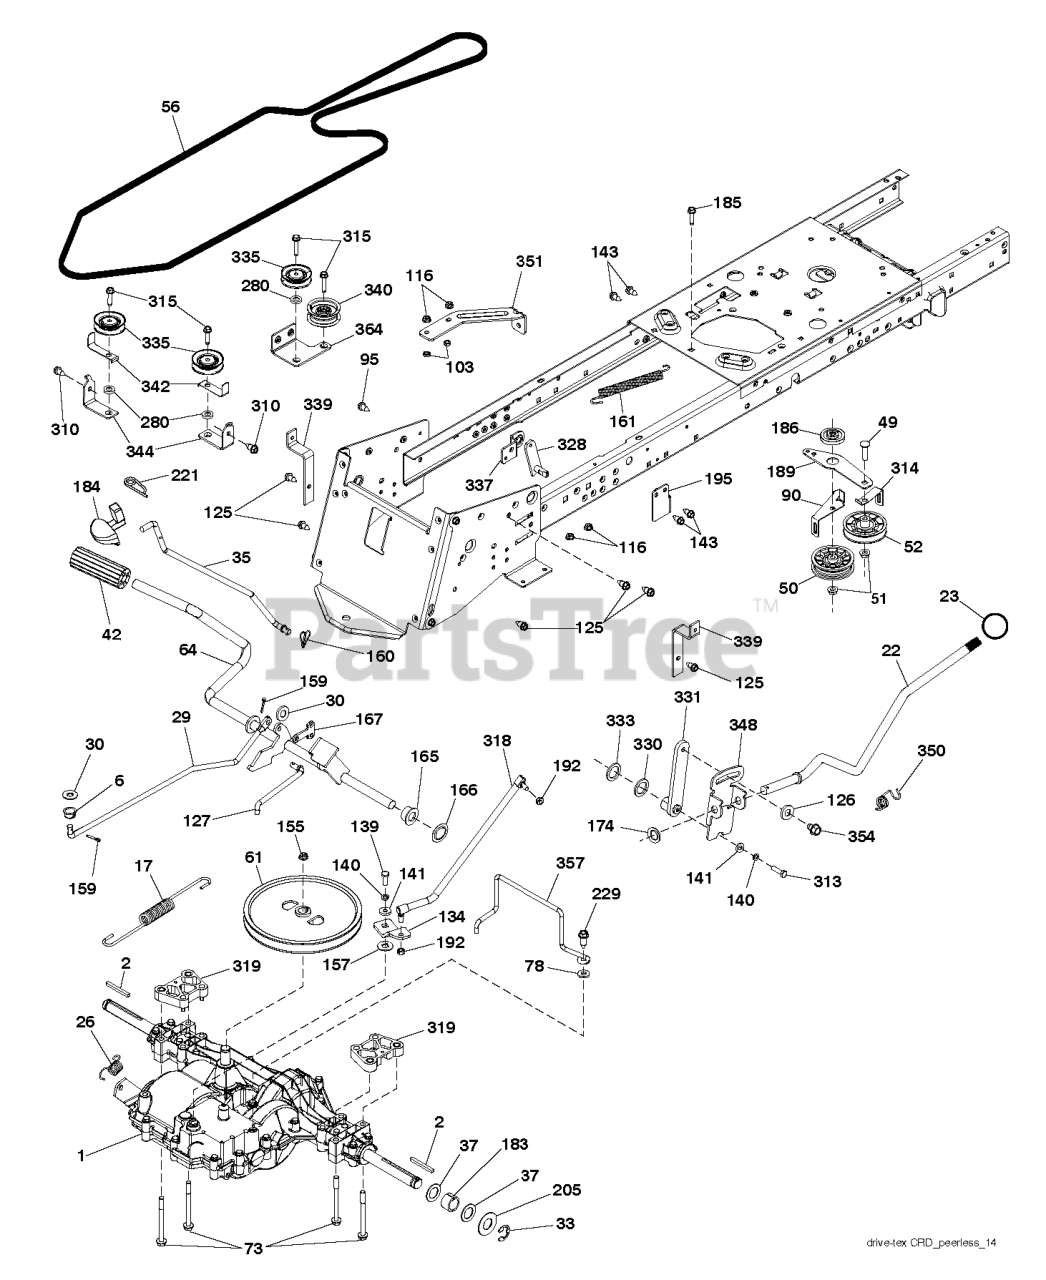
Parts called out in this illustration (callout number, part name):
2	SQUARE KEY
6	BUSHING.SNAP.NYL.BLK.
17	SPRING SPRING BRAKE GEAR CRD
22	ROD ROD SHIFT CRD TEX
23	KNOB.DUCKHEAD.1/2
26	SPRING,BRAKE RETURN
29	ROD.BRAKE.GEAR.CRD.TEX
30	WASHER
35	ROD.CNTRL.PARK.PREDATOR.LT.TEX
42	PEDAL COVER T
45	LOCKNUT.NYLOC.1/4-20
48	BOLT.3/8-16X1.50
51	NUT LOCK FLG 3/8-16 UNC
56	BELT BELT V CRD GEAR
61	PULLEY
64	SHAFT.ASM.PEDAL.BRAKE.
73	BOLT.FLANGED
90	BRACKET KEEPER BELT CLUTCHING
95	SCREW, 3/8-16X3/4
103	JAM NUT TI
116	NUT LOCK HEX FLANGE 5/16-18
124	BOLT.SHOULDER.5/16-18X
125	SCREW
126	WASHER.SRRTD.5/16
127	RP.LINK.CLUTCH.GROUND.DRIVE
139	BOLT 1/4-28X3/4
140	LOCKWASHER
141	WASHER LT
143	SCREW LT
155	RETAINING RING LT
157	WASH-SHFT PLT LT
159	COTTER PIN
160	RETAINER CLIP
161	SPRING, RETURN LT
165	BUSHING.SHAFT.BRAKE.HAND
166	NUT.PUSH.625
167	LATCH.BRAKE.SPRING
183	SPACER AXLE
184	HANDLE.PARKING.BRK.PRED.LT.RED
186	SPACER.RETAINER
187	WASHER 12/32X2X10GA
189	BELLCRANK BELLCRANK GROUNDDRI
192	NUT LOCK CENTER 1/4 -28 FNTHD
221	RETAINER.SPRING.CLIP.H
229	SCREW 5/16-18X1
300	PULLEY.V-IDLER.
310	SCREW LT
313	BOLT
314	RETAIN BELT
315	BOLT.5/16-18X1.25
318	GEAR LINK SHIFT GEAR
319	SPACER SPACER TRANSAXLE TEX C
321	IDLER PULLEY
326	BOLT CARRIAGE
328	SHAFT SHAFT SHIFT FRONT
329	BRACKET.SHIFT.MOUNT
330	WASHER.NYL.7/8IDX.105"HYD CR
331	RB HUB.SHIFT
332	BOLT
333	WASHER.WAVE.SPRING
337	BRACKET BRACKET SUPT SHIFT CR
339	STRAP STRAP TORQUE K46 CRD TE
340	IDLER.FLAT.2.25.INCH
342	BELT GUIDE
343	WASHER T
344	BRACKET BRACKET IDLER CRD TEX
348	BRACKET.PIVOT.LEVER
349	WASHER
350	SHIFT SPRING
351	BRACKET BRACKET DECK SWAY
354	CAPSCREW.HXHD.FLG.5/16-18X.625
357	KEEPER KEEPER
